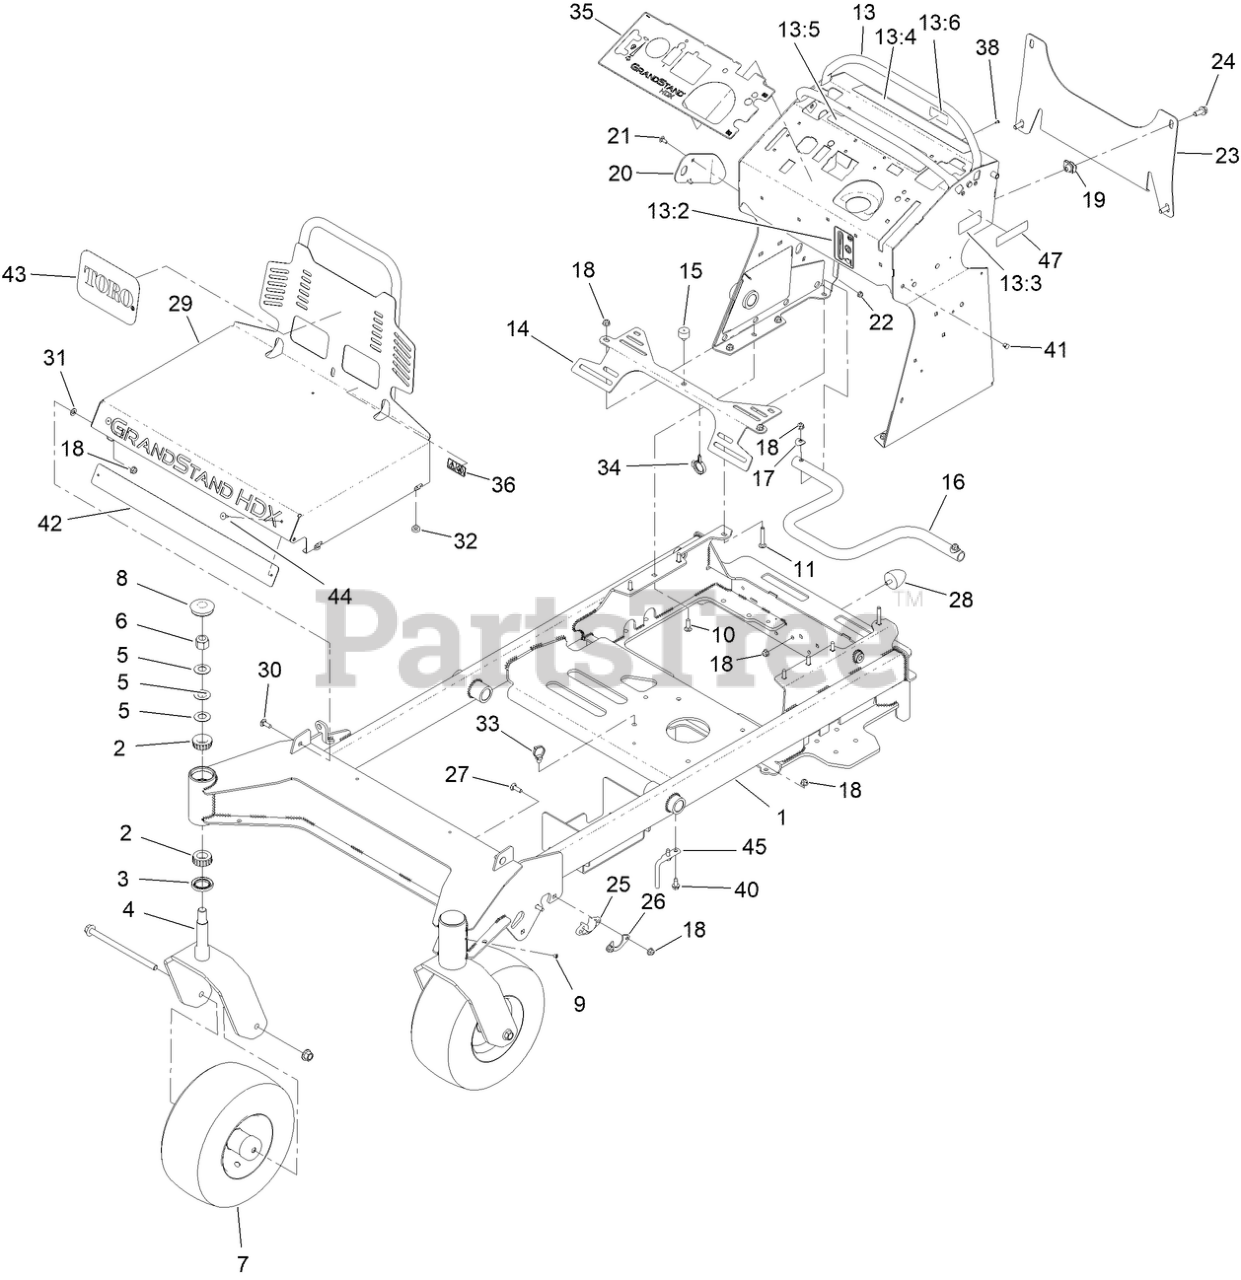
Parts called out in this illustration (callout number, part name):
1	FRAME-72 [RED]
2	BEARING-ROLLER, TAPERED
3	SEAL-GREASE
4	CASTER-FORK [RED]
5	WASHER-BELLVILLE
6	NUT-LOCK, NI
7	ASM-WHEEL BRGS AXLE 13X6.50-6
8	CAP,GREASE
10	BOLT-CARR
11	BOLT-CARR
13	TOWER DECAL ASM
13:2	DECAL-OIL LEVEL
13:3	DECAL-FILL, FUEL
13:4	DECAL-WARNING
13:5	DECAL-CONTROLS
13:6	DECAL - FUSE
14	GUARD-FAN
15	BUMPER-GROMMET
16	TUBE-FUEL TANK MOUNT
17	WASHER
18	NUT-HF, NI
19	NUT-TINNERMAN
20	PLATE-STRIKER
21	SCREW-CARR
22	NUT-HF
23	BRACKET-CROSS
24	SCREW-HHF
25	BEARING-FLANGE
26	GUSSET-LIFT, DECK
27	SCREW-CARR
28	BUMPER-RUBBER
29	ASM-ENGINE GUARD [SERVICE]
30	BOLT-CARR
31	SPACER-NYLON
32	BUMPER
33	CLIP-TIE
34	CLAMP-R
35	DECAL-PANEL CONTROL, BRIGGS
36	DECAL-WARNING, NO RIDERS
38	RIVET-POP
40	SCREW-HWHTF
41	DOME PANEL PLUG
42	PLATE-BACKING
44	RIVET-POP
45	GUIDE-BELT
47	DECAL-SPARK ARRESTER
